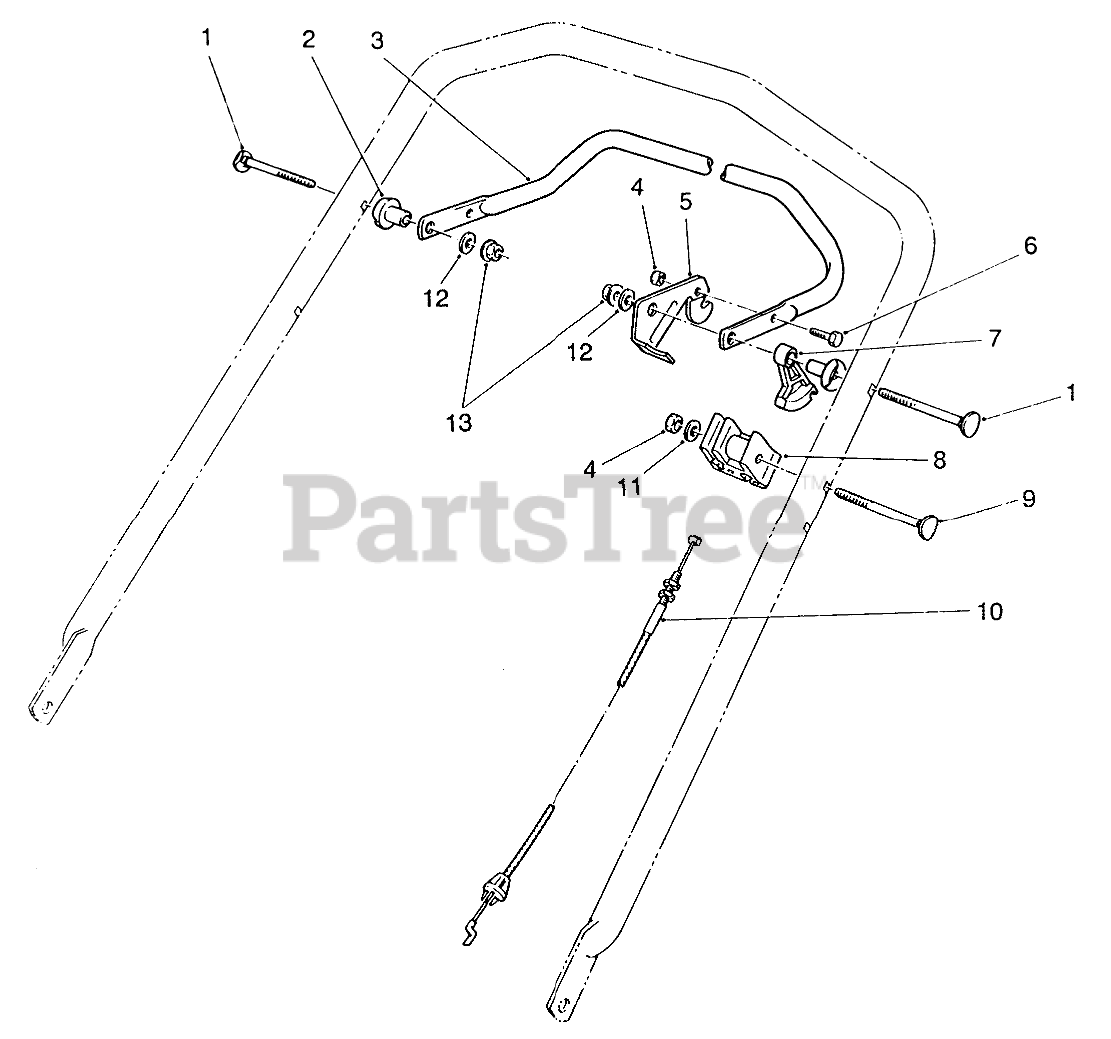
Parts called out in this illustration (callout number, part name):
1	SCREW-HANDLE
2	SPACER-SUPPORT
3	Bar-Control
4	NUT-LOCK, NI
5	CONTROL LEVER
6	SCREW-HH
7	LEVER-TRACTION
8	SUPPORT-CABLE
9	SCREW-HANDLE
10	TRACTION CABLE
11	WASHER-FLAT
12	WASHER-PLAIN
13	NUT-LOCK, NI
